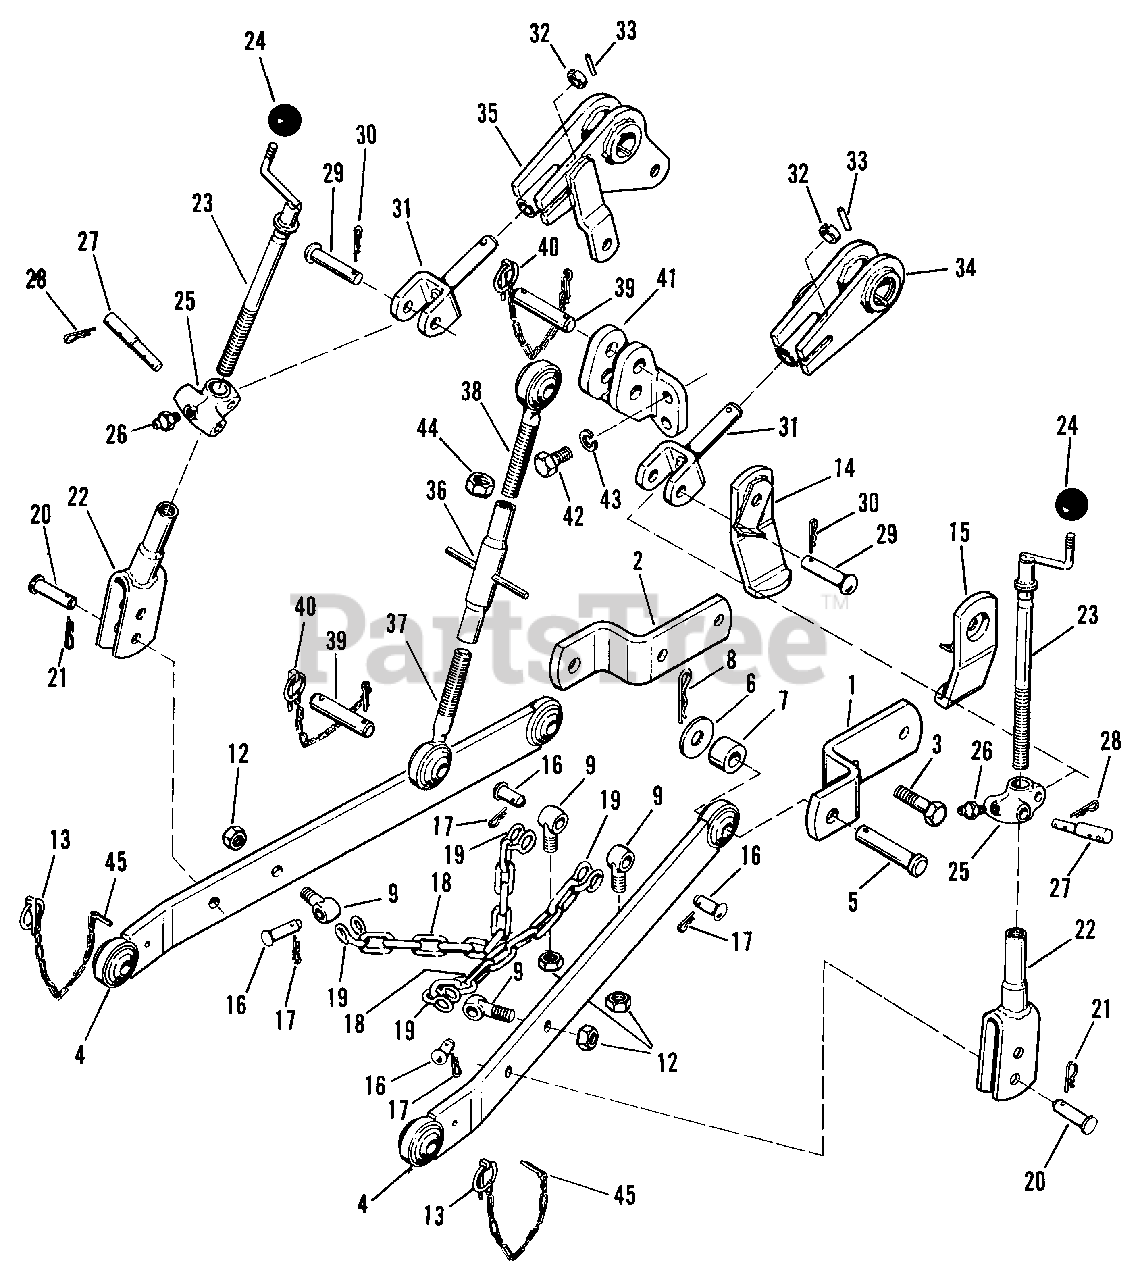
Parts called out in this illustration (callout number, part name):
1	Pull Link Strap, R.H.
2	Pull Link Strap, L.H.
3	Hex Capscrew, 1/2"-13 x 2" lg.
4	Pull Link Assembly
8	Hairpin Clip
9	Eyebolt, 1/2"-20
10	Lock Washer, 1/2"
11	Hex Nut, 1/2"-20
12	Hex Nut, Center Lock 1/2"-20
13	Retaining Pin
14	Rub Bar Assembly, L.H.
15	Rub Bar Assembly, R.H.
16	Pin
17	Hairpin Clip
18	Chain, 9 links
21	Hairpin Clip
22	Clevis Assembly
23	Link Assembly
26	Grease Fitting
28	Hairpin Clip
30	Hairpin Clip
31	Clevis Assembly
34	Lift Arm Assembly, R.H.
35	Lift Arm Assembly, L.H.
36	Upper Link Assembly
37	Stud Assembly, R.H.
38	Stud Assembly, L.H.
40	Retaining Pin
41	Upper Link Support
42	Hex Capscrew, 7/16"-14 x 1-1/4" lg.
43	Lock Washer, 7/16"
44	Hex Nut. 3/4"-10 L.H.
45	Cotter Pin
